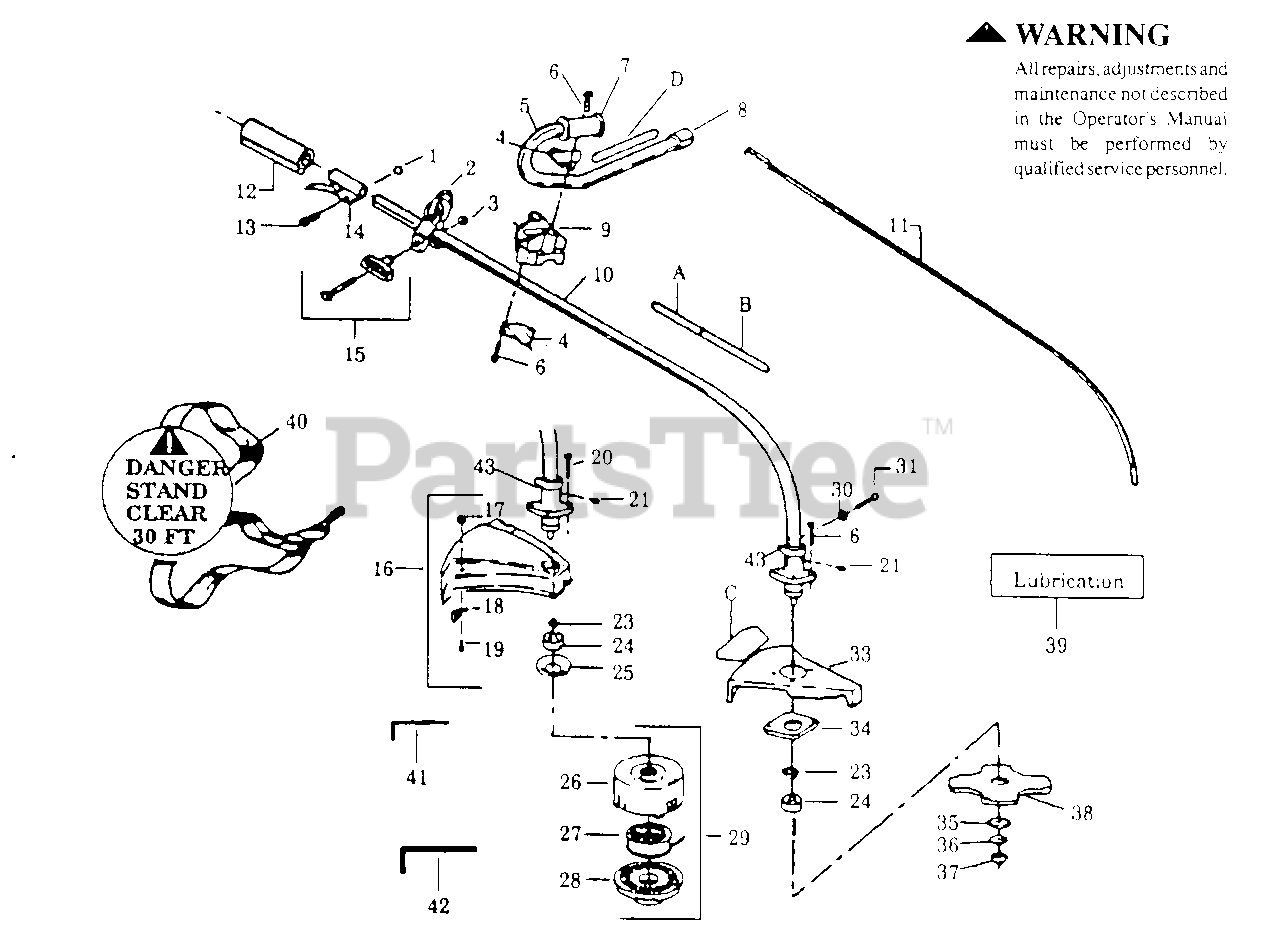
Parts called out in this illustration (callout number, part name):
2	Clamp Harness Assy.
4	Handlebar Bracket
5	Handlebar
7	Handlebar Grip
8	Handlebar Cap
9	Handlebar Clamp
10	Drive Shaft Housing
11	Drive Shaft
12	Drive Shaft Grip
14	Throttle Lever Assy. (Inc.1,13)
15	"T" Handle Kit
16	Shield Kit Assy. (Inc.17 - 19)
17	Locknut
18	Line Limiter
20	Screw
24	Dust Cup
25	Grass Washer
26	Hub Assy.
27	Spool w/Line
29	Cutting Head Assy. (Inc.26 - 28)
34	Shield Retention Plate
36	Washer
38	Weed Blade
39	Shaft Lubrication
40	Shoulder Strap
41	Hex Wrench (5/32)
42	Hex Wrench (3/16)
43	Bearing Housing Assy. (Inc.23 & 24)
